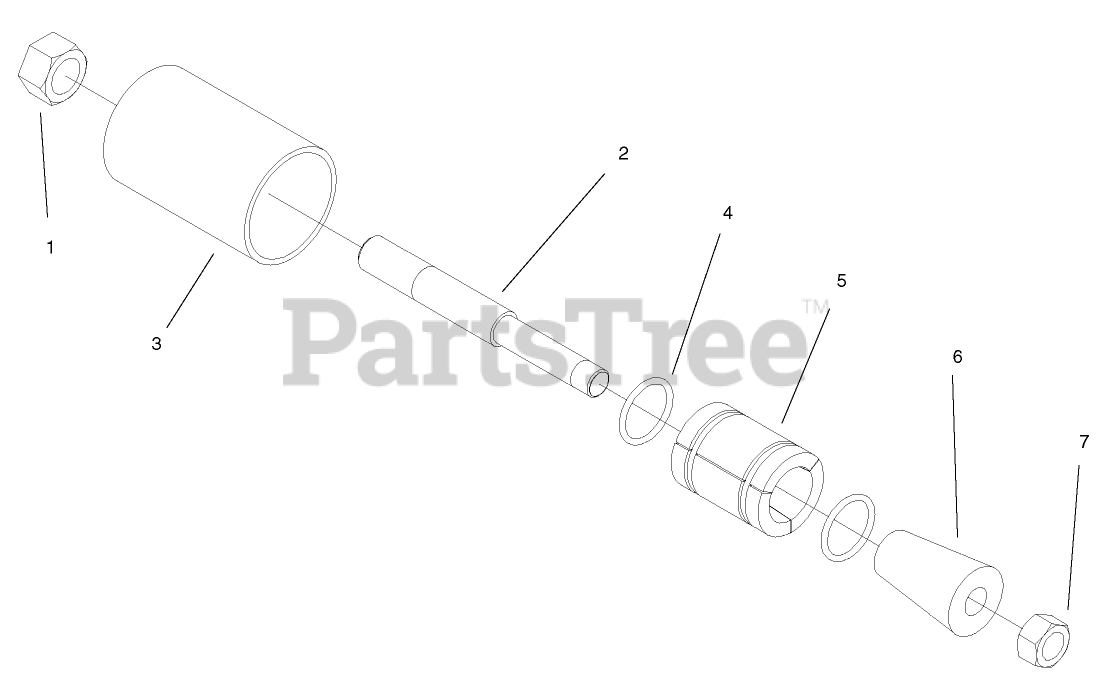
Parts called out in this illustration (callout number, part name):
1	NUT-HEX
2	ROD-PULLER
3	GRIP-OUTER
4	O-RING
5	GRIP-INNER
6	CONE-PULLER
7	NUT-HEX
